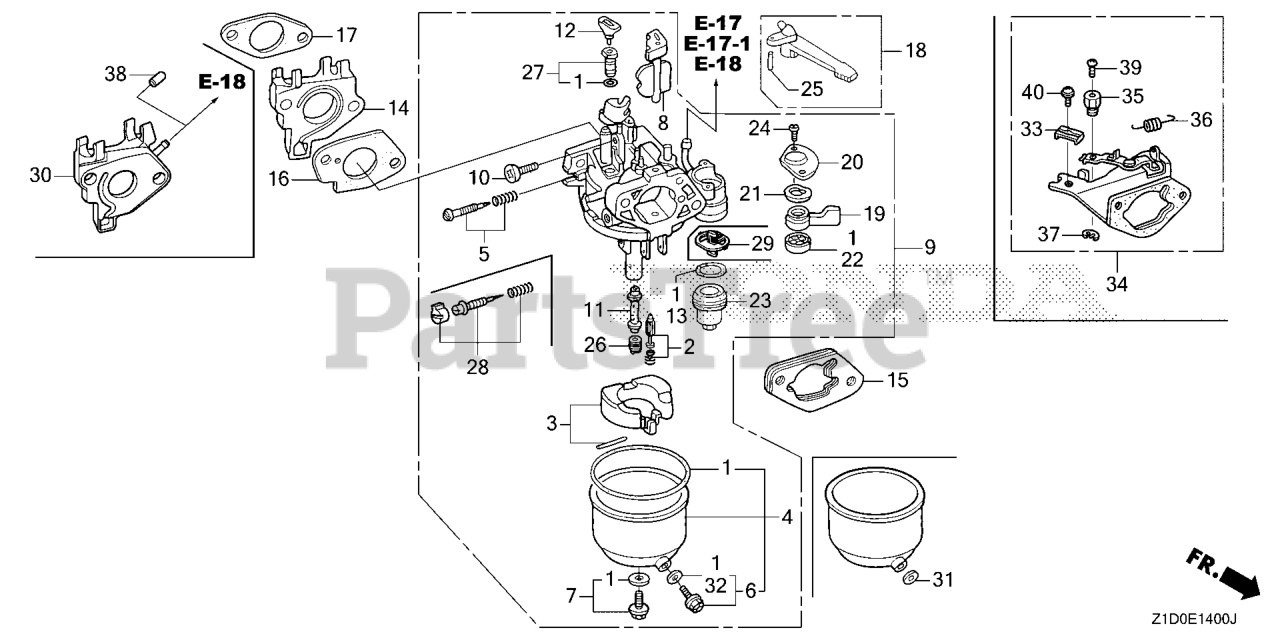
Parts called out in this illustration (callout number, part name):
1	GASKET SET (INCLUDE 16173-001-004) (INCLUDES 16173-001-004)
2	VALVE SET, FLOAT
3	FLOAT SET (CARBURETOR NO.)
4	CHAMBER SET, FLOAT
6	SCREW SET, DRAIN
7	SCREW SET (CARBURETOR NO.)
8	CHOKE SET
9	CARBURETOR ASSY. (BE21N A)
10	SCREW, THROTTLE STOP
11	NOZZLE, MAIN
12	COLLAR, SET
13	GASKET, FUEL STRAINER CUP
14	INSULATOR, CARBURETOR
15	SPACER, CARBURETOR
16	GASKET, CARBURETOR
17	GASKET, INSULATOR
18	LEVER, CHOKE (STD)
19	LEVER, VALVE
20	PLATE, LEVER SETTING (CARBURETOR NO.)
21	SPRING, PETCOCK LEVER (CARBURETOR NO.)
22	GASKET, VALVE
23	CUP, FUEL STRAINER
24	SCREW, PAN (3X6)
25	PIN, SPRING (2X12)
26	JET, MAIN (#85) Use up to Engine SN BE81B B.
26	JET, MAIN (#88) Use up to Engine SN BE81B B.
26	JET, MAIN (#90) Use from Engine SN BE81B C.
27	JET SET, PILOT (#40) (ADVENTURE GREEN) (CARBURETOR NO.)
28	SCREW SET (Honda Code 4219879). (CARBURETOR NO.)
29	FILTER, CUP (CARBURETOR NO.)
31	WASHER, PLAIN (6.2X10.7 DRAIN) (CARBURETOR NO.)
